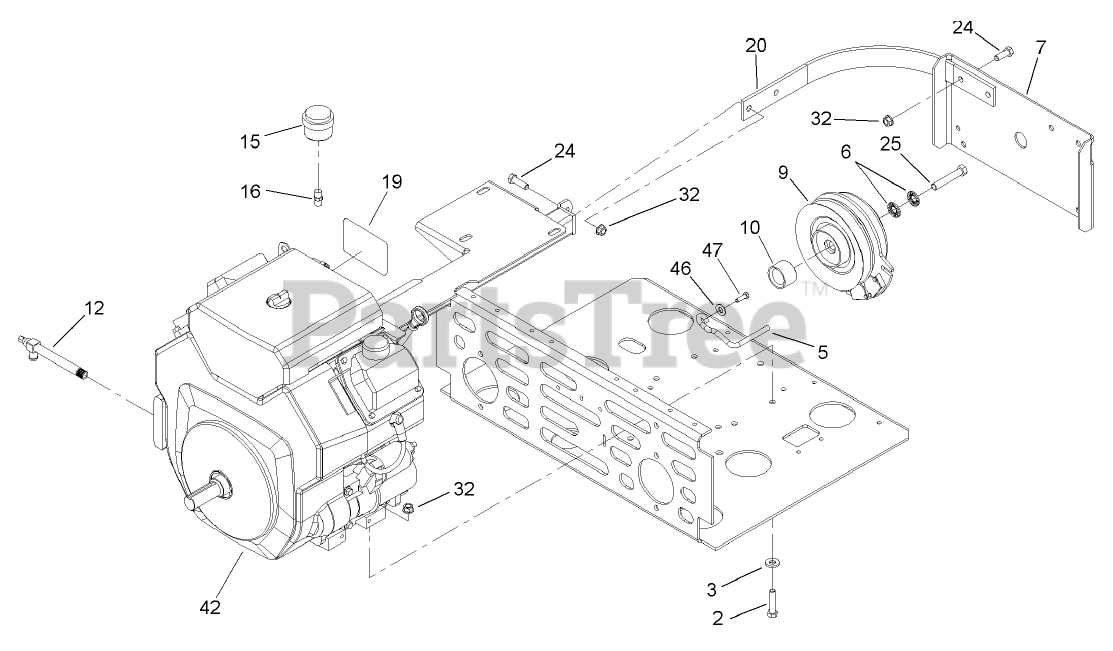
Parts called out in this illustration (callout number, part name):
2	SCREW-HH
3	WASHER-BELLEVILLE
5	ROD-BELT
6	WASHER-SPRING
7	GUARD-CLUTCH
9	Clutch
10	SPACER-CLUTCH
12	VALVE-OIL DRAIN, LONG
15	INDICATOR-FILTER, AIR
16	ADAPTER-INDICATOR
20	BRACKET-GUARD, TOP
24	SCREW-HH
25	SCREW-HH
32	NUT-HHF, WHIZ
46	WASHER-FLAT
47	SCREW-HH
